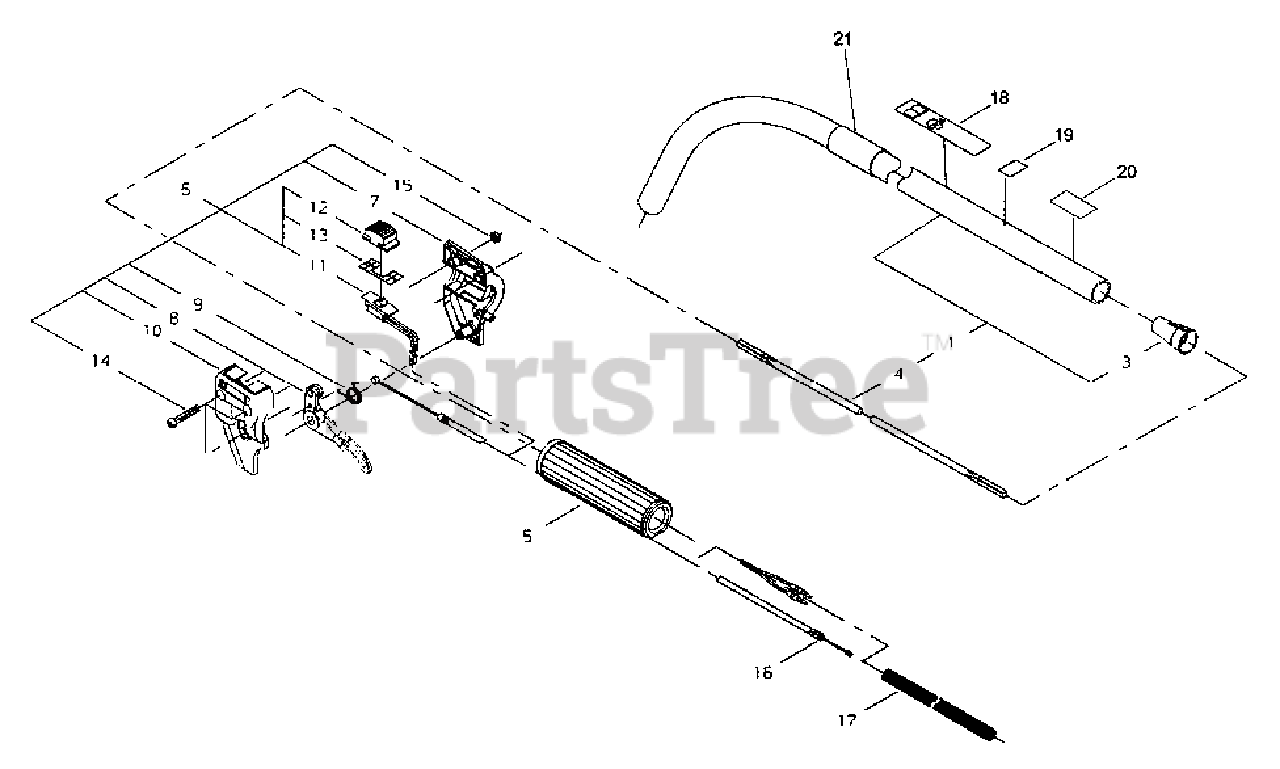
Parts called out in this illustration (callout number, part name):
1	MAIN PIPE ASSY
4	DRIVESHAFT - FLEXIBLE
5	GRIP
6	THROTTLE LEVER ASSY
7	CONTROL HANDLE - RIGHT
8	TRIGGER, THROTTLE
9	SPRING, RETURN
10	CONTROL HANDLE - LEFT
11	SWITCH
12	KNOB, SWITCH
13	PLATE, SWITCH
14	SCREW M5×30
15	NUT M5
16	CABLE, THROTTLE
17	TUBE, FLEXIBLE
18	LABEL, CAUTION (NON-BLADE CAPABLE)
19	LABEL, HANDLE
20	LABEL, OUTER TUBE
